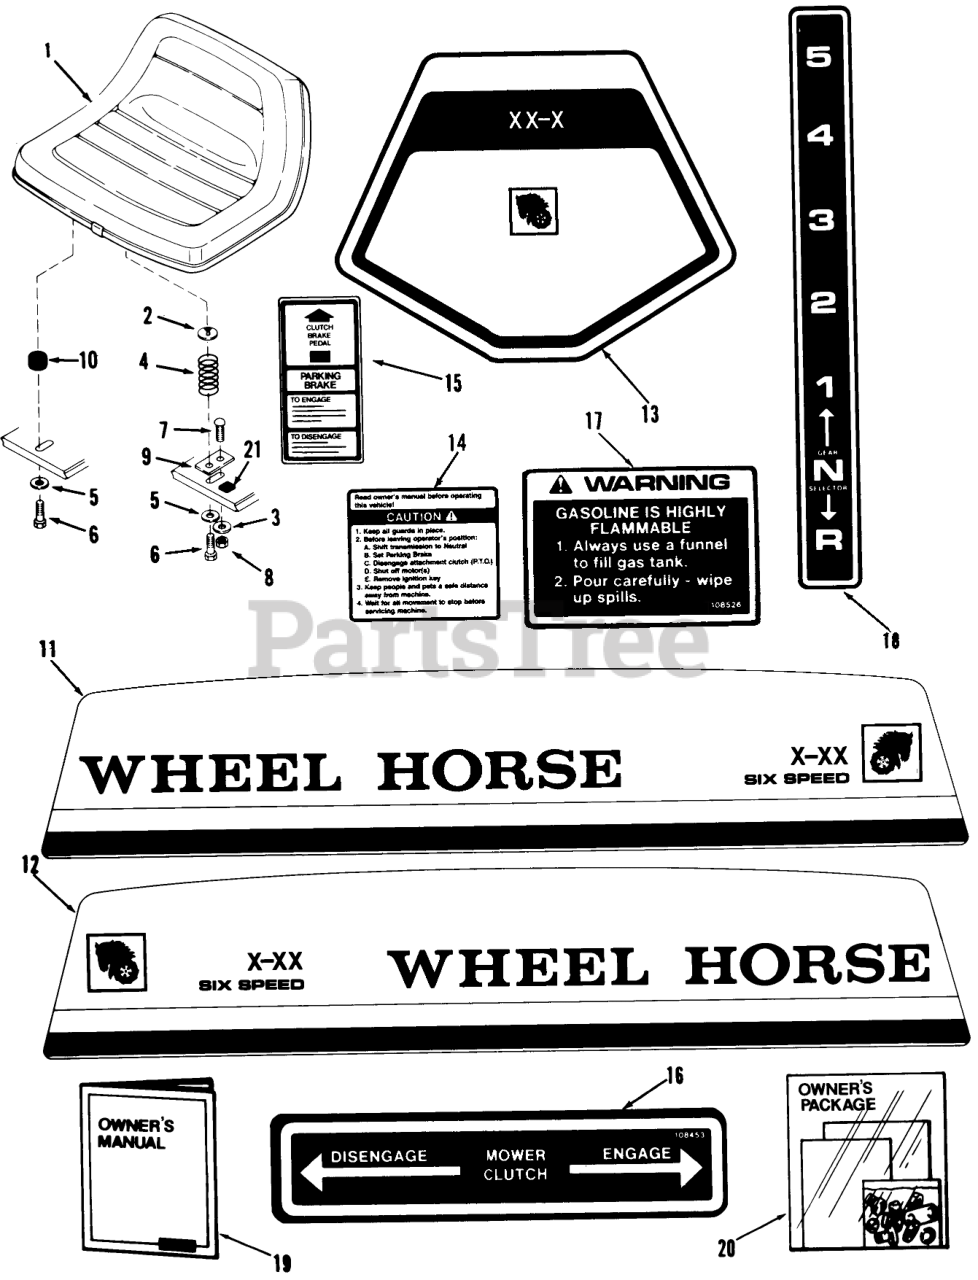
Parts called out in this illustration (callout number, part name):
5	WASHER 5/16 SAE
7	CARRIAGE BOLT -4
19	Owner-s Manual (Rider)
19	Owner-s Manual (Mower)
20	New Rider Loose Parts Pkg A-81E
20	New Rider Loose Parts Pkg A-111
20	New Rider Loose Parts Pkg A-51
20	New Rider Loose Parts Pkg A-81R
21	BUMPER
